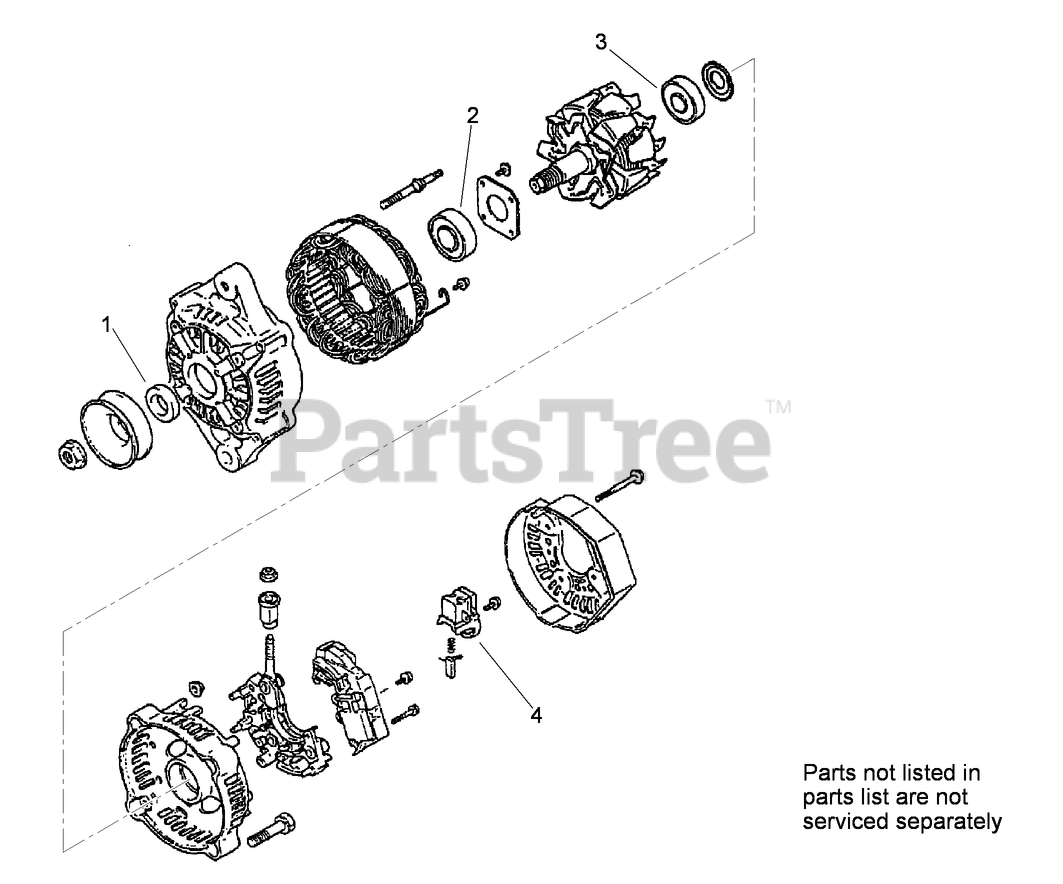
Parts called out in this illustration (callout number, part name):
1	COLLAR
2	BEARING
3	BEARING
4	BRUSH HOLDER ASM
